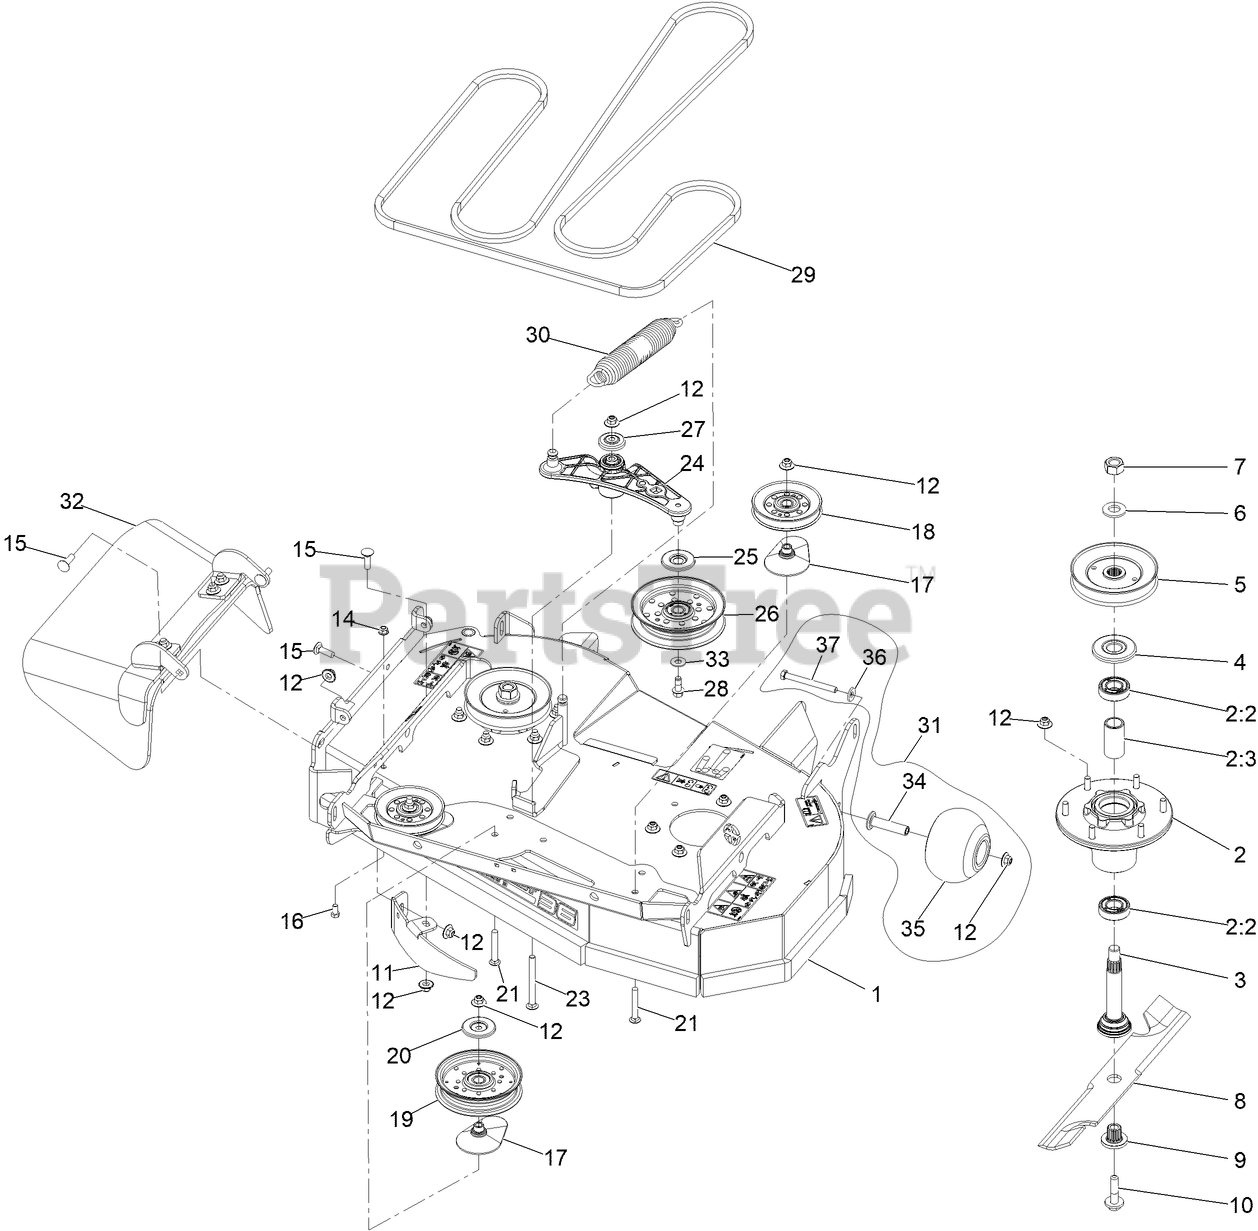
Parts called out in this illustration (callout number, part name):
1	ASM, 36" DECK W/ DECALS
2	ASM-CUTTER HSG WITH BEARINGS
2:2	BEARING-BALL
2:3	SPACER-BEARING
3	ASM-SPINDLE AND SEAL
4	GUARD,BEARING TOP .989
5	SHEAVE-BLADE DRIVE
7	NUT-HEX
9	BUSHING,SPLINED
10	SCREW,SEMS 1/2-20 X 2.19
11	BAFFLE, DOGLEG
12	Nut-Nyloc 3/8-16 Flg
14	NUT-HF, NI
15	BOLT-CARR
16	SCREW-HH
17	SPACER-PULLEY
18	Idler - V 4.13 Eod-A
19	PULLEY-IDLER, FLAT
20	SHIELD-DUST
21	SCREW-CARR
23	SCREW-CARR
24	ASM.-ARM, IDLER
25	SHIELD-GUARD, DUST
26	IDLER-PULLEY, FLAT
27	GUARD-TOP
28	SCREW-HFH
30	SPRING-EXTENSION
31	KIT, ANTI-SCALP ROLLER
32	RUBBER DEFLECTOR ASM
33	WASHER-FLAT
34	AXLE, ROLLER
35	ROLLER-SCALP, ANTI
36	WASHER-BELLEVILLE
37	SCREW-HH 3/8-16 X 3 3/4 GR 8
